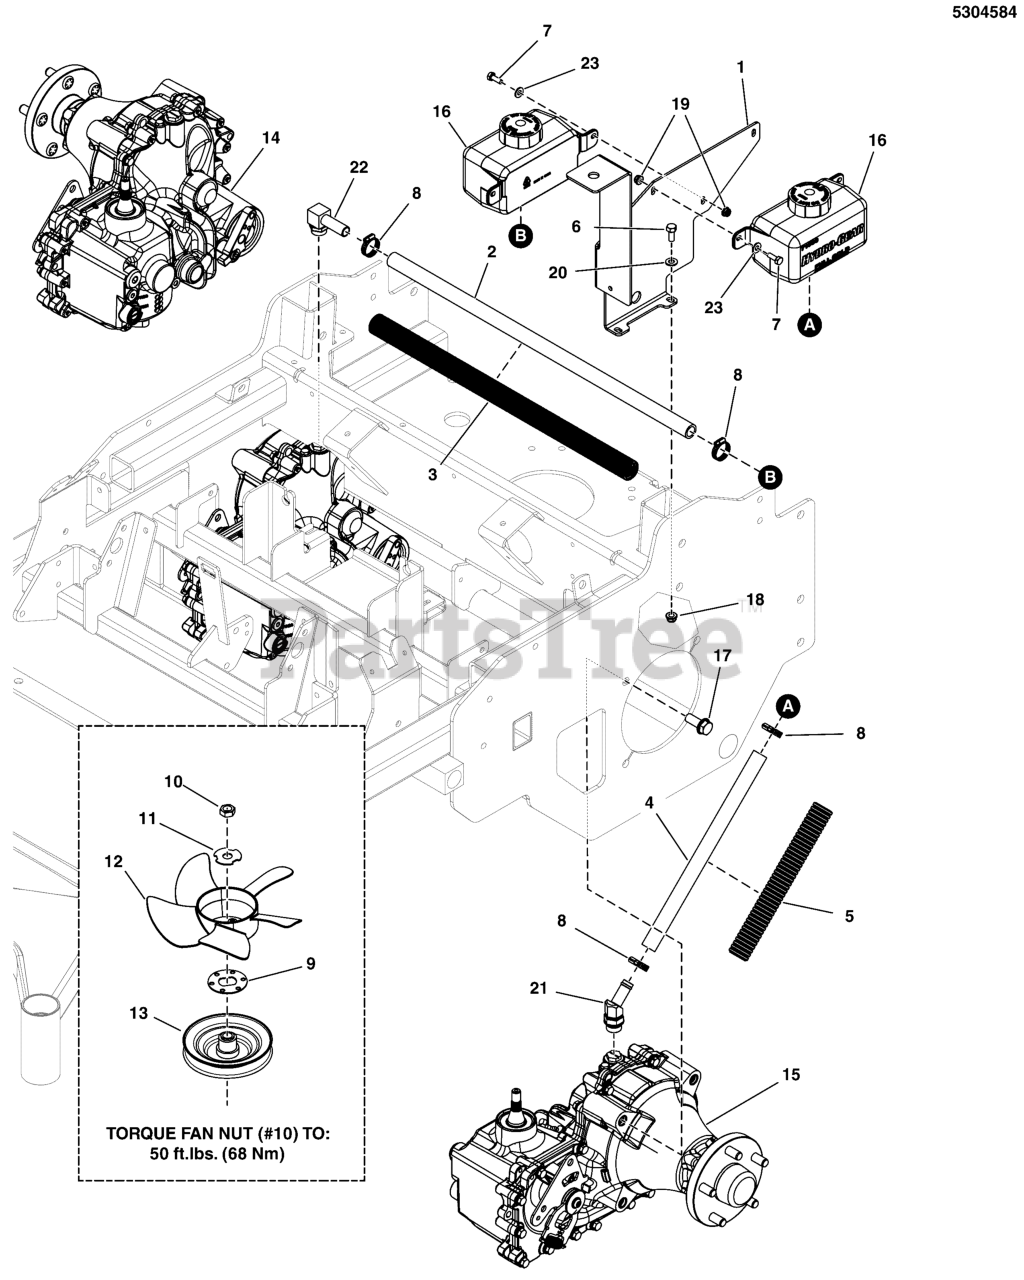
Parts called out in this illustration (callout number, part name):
1	PLATE, HYDRO MOUNT - OG, S200XT - BLK
2	HOSE, 5/8, PUSH-LOCK, 28.00
3	LOOM, CONVOLUTED SPLIT, 1 ID - 23 LONG
4	HOSE, 5/8, PUSH-LOCK, 13.00
5	LOOM, CONVOLUTED SPLIT, 1 ID - 10 LONG
6	BOLT, 5/16-18 X 3/4 GD5
7	BOLT, 1/4-20 X 3/4 GD5 CZ
8	CLAMP, #10 HOSE, STAINLESS
9	SPACER, ANTI ROTATE, ZT5400
10	NUT, ZT5400
11	WASHER, ZT5400, SLOTTED
12	FAN, ZT5400
13	PULLEY, ZT5400 (53177)
14	TRANSAXLE, ZT5400, RH, 1015-1024R
15	TRANSAXLE, ZT5400, LH, 1015-1024L
16	HYDRO TANK, HYDRO-GEAR 71938, 1 LITER
17	BOLT, 1/2-13 X 1-1/4, SF, PLT W/PATCH
18	NUT, 5/16-18 HEX NYLOCK FLANGE
19	NUT, 1/4-20 HEX NYLOCK FLANGE
20	WASHER, 5/16" SAE
21	FITTING, 45, 5/8 TUBE TO 7/8-14 O-RING
22	FITTING, EBLOW, 7/8-14 O-RING-5/8" TUBE
23	WASHER, 1/4 SAE
